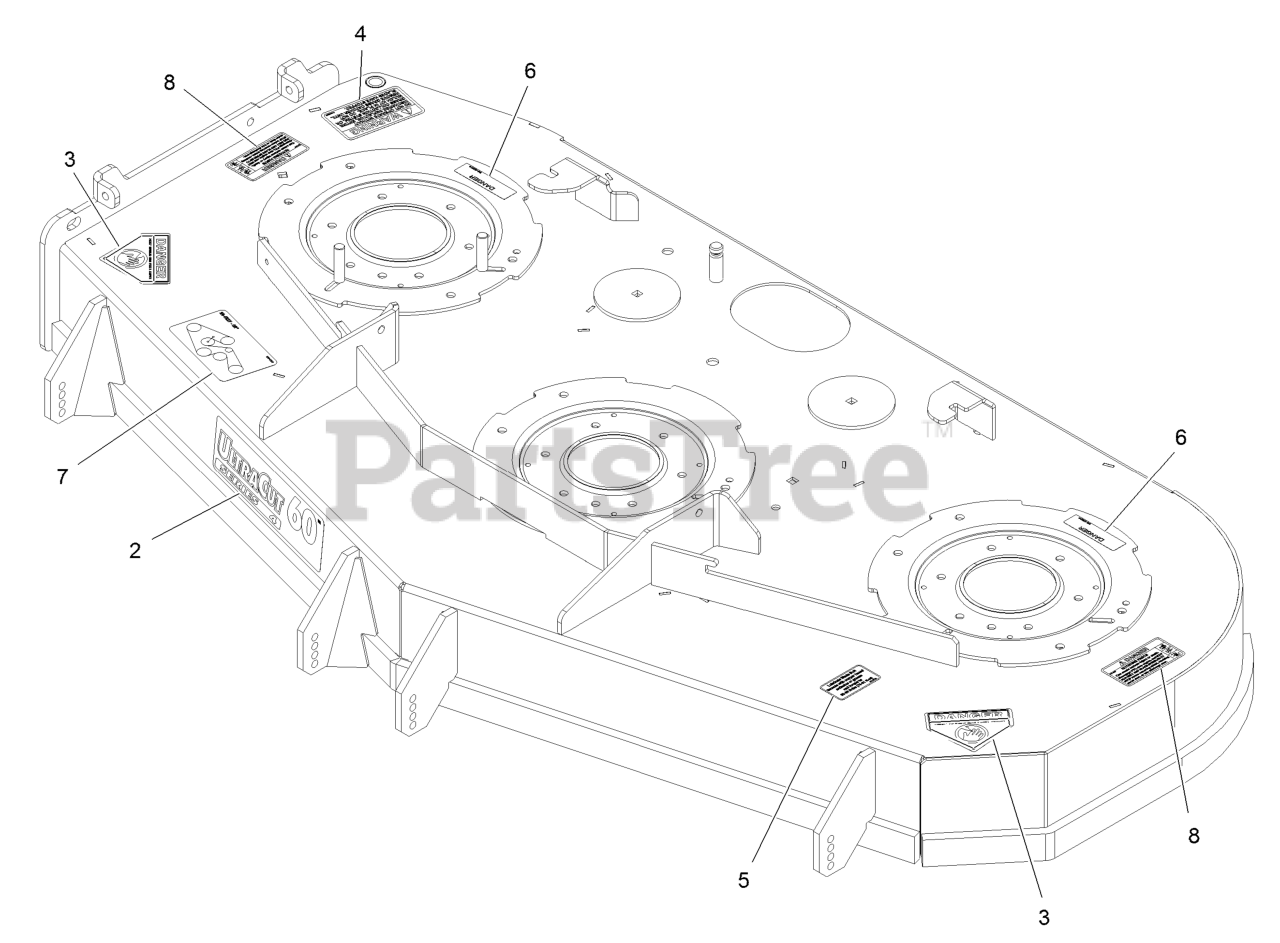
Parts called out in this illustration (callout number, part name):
2	DECAL,ULTRACUT 60 SERIES
3	DECAL-DANGER
4	DECAL-WARNING, DISCHARGE
5	DECAL,BOLT TORQUE
6	DECAL-COVER, MISSING
7	DECAL-BELT ROUTING
8	DECAL-ROTATING PARTS
